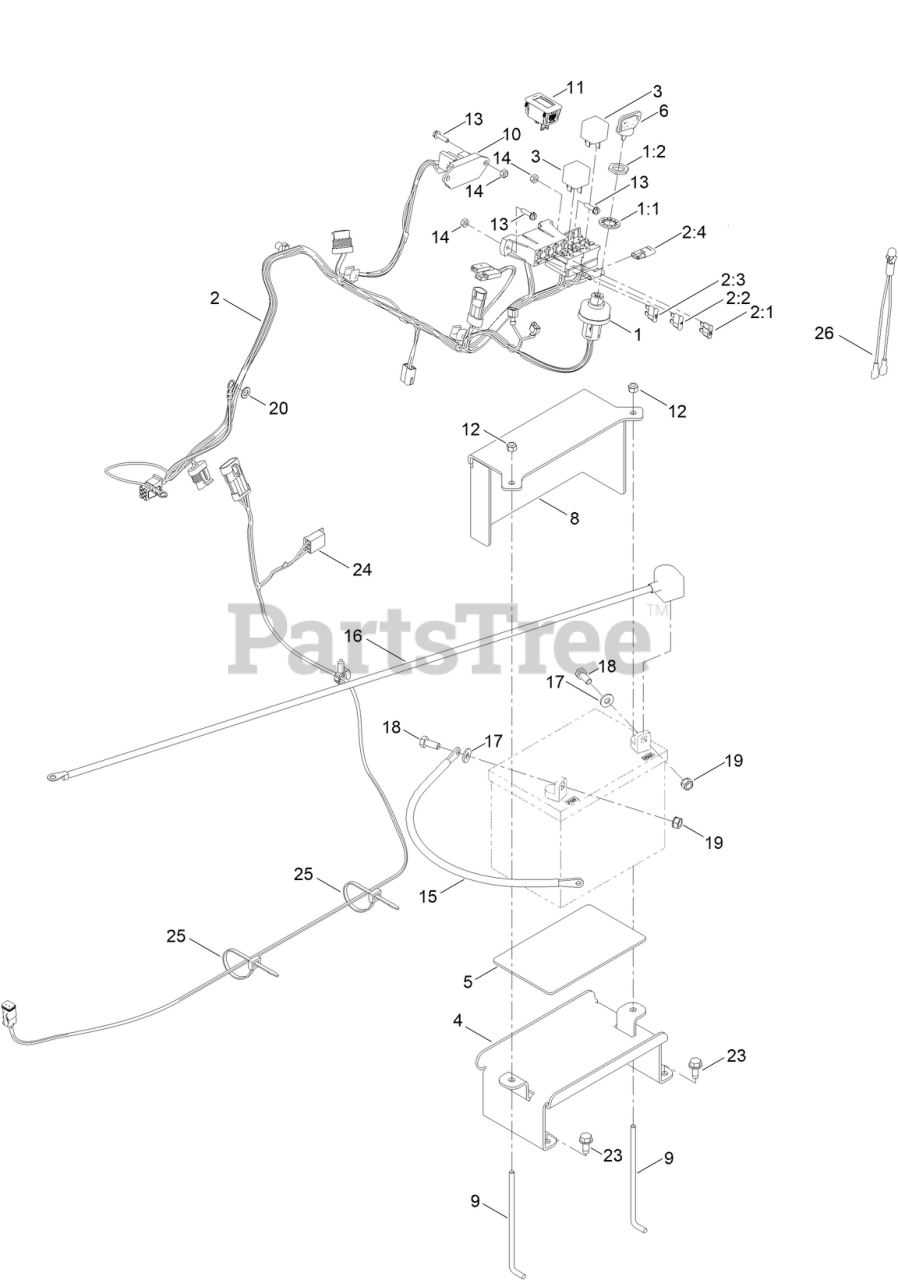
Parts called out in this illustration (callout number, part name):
1:1	WASHER-LOCK
2	HARNESS-WIRE
2:1	FUSE-BLADE, 30 AMP
2:2	FUSE-BLADE, 5 AMP
2:3	FUSE-BLADE, 20 AMP
2:4	CAP-PLUG
3	RELAY
4	TRAY-BATTERY
5	PAD-SKID, ANTI
6	KEY-IGNITION
8	COVER-BATTERY
9	HOLDOWN-BATTERY
10	MODULE-DELAY
11	HOURMETER
12	NUT-LOCK, NI
13	SCREW-HWH
14	NUT-LOCK, NI
15	CABLE-BATTERY, POSITIVE
16	CABLE-BATTERY, NEGATIVE
17	WASHER-FLAT
18	SCREW-HH
19	NUT-KEPS
20	WASHER-LOCK
23	SCREW-HWHTF
24	HARNESS-WIRE
25	TIE-CABLE
26	INDICATOR-LED, RED
